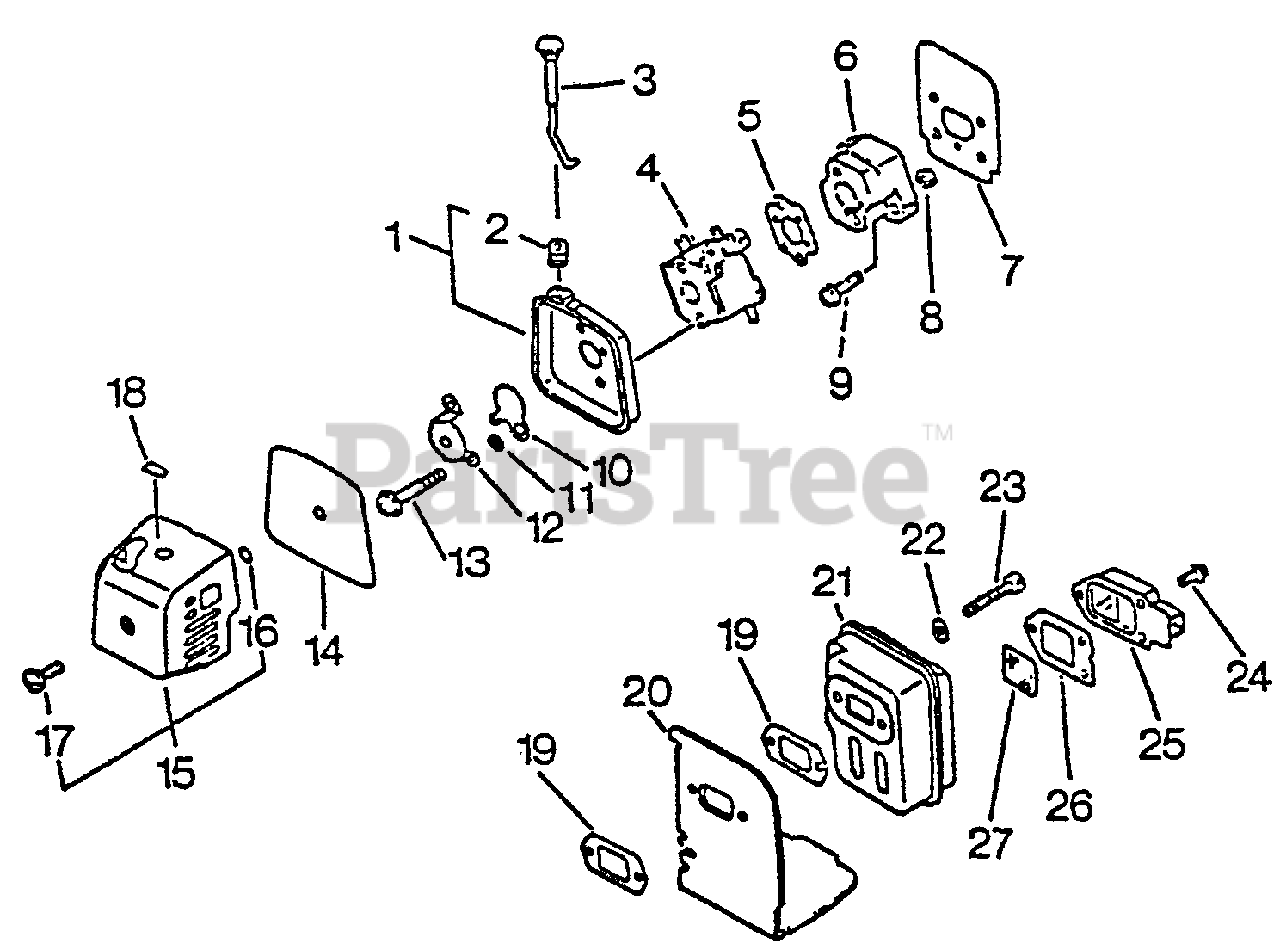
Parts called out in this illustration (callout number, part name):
1	CASE, AIR FILTER
2	GROMMET, CHOKE
3	ROD, CHOKE
4	CARBURETOR - C1U-K16
5	GASKET, INTAKE
6	INSULATOR, INTAKE
7	HEAT SHIELD, INTAKE
8	NUT M5
9	SCREW 5×20
10	SHUTTER, CHOKE
11	WASHER 5.2×8×0.8T
12	CASE, AIR FILTER
13	SCREW 5×57
14	FILTER, AIR
15	AIR FILTER COVER ASSY
18	LABEL, CHOKE
19	GASKET, EXHAUST
20	COVER, EXHAUST
21	MUFFLER ASSY
22	WASHER, FLAT 5.5×10×0.8
23	BOLT 5×55
24	SCREW 4×10
25	GUIDE, EXHAUST - INNER
26	GASKET, EXHAUST
27	SCREEN, SPARK ARRESTER
